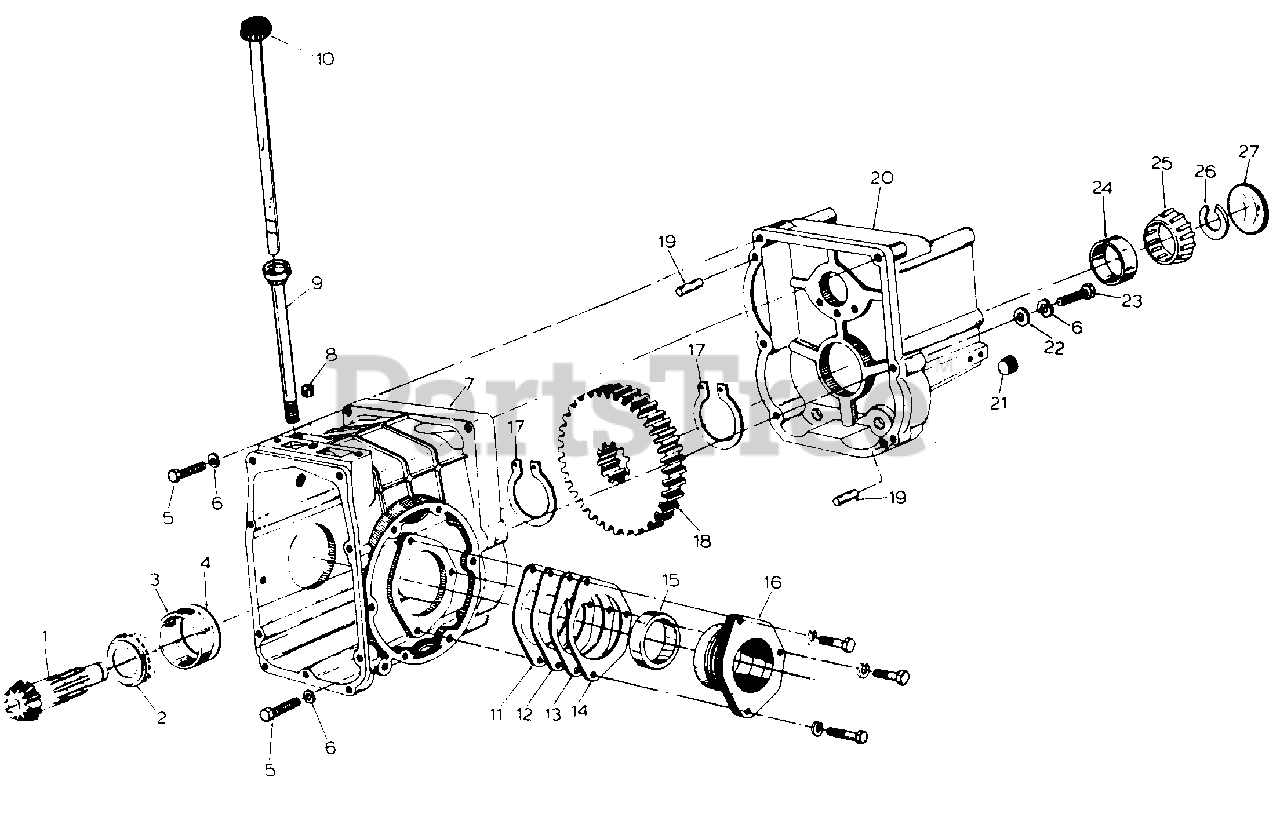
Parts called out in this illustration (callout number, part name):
1	Shaft, Bevel Pinion
2	Bearing Assy, Pinion Shaft Rear Cone
3	Bearing, Pinion Shaft Rear Cup
4	Shim, Rear Bearing Cup, .004
5	Bolt, 7/16 X 1-3/4 Type 5
6	Washer, 7/16 ID Belleville
7	Housing Assy, Rear
8	Plug, Breather
9	Tube, Dipstick
10	Dipstick Assy
11	Shim, Bearing Retainer, .004
12	Shim, Bearing Retainer, .007
13	Shim, Bearing Retainer, .0149
14	Shim, Bearing Retainer, .0299
15	Bearing, Cup
16	Retainer, Bearing
17	Ring, Retaining
18	Gear, Constant Mesh -68T
19	Pin, 3/8 X 5/8 Dowel
20	Housing, Adapter
21	Plug, 1/2-14 Pln H/Hd Pipe
22	Washer, .438 X .875 X .064
23	Bolt, 7/16 X 2-1/2 Type 5
24	Bearing, Pinion Shaft Front Cup
25	Bearing, Pinion Shaft Front Cone
26	Ring, Front Bearing Retainer, .125
27	Plug, 2-1/8 Pln Expansion
